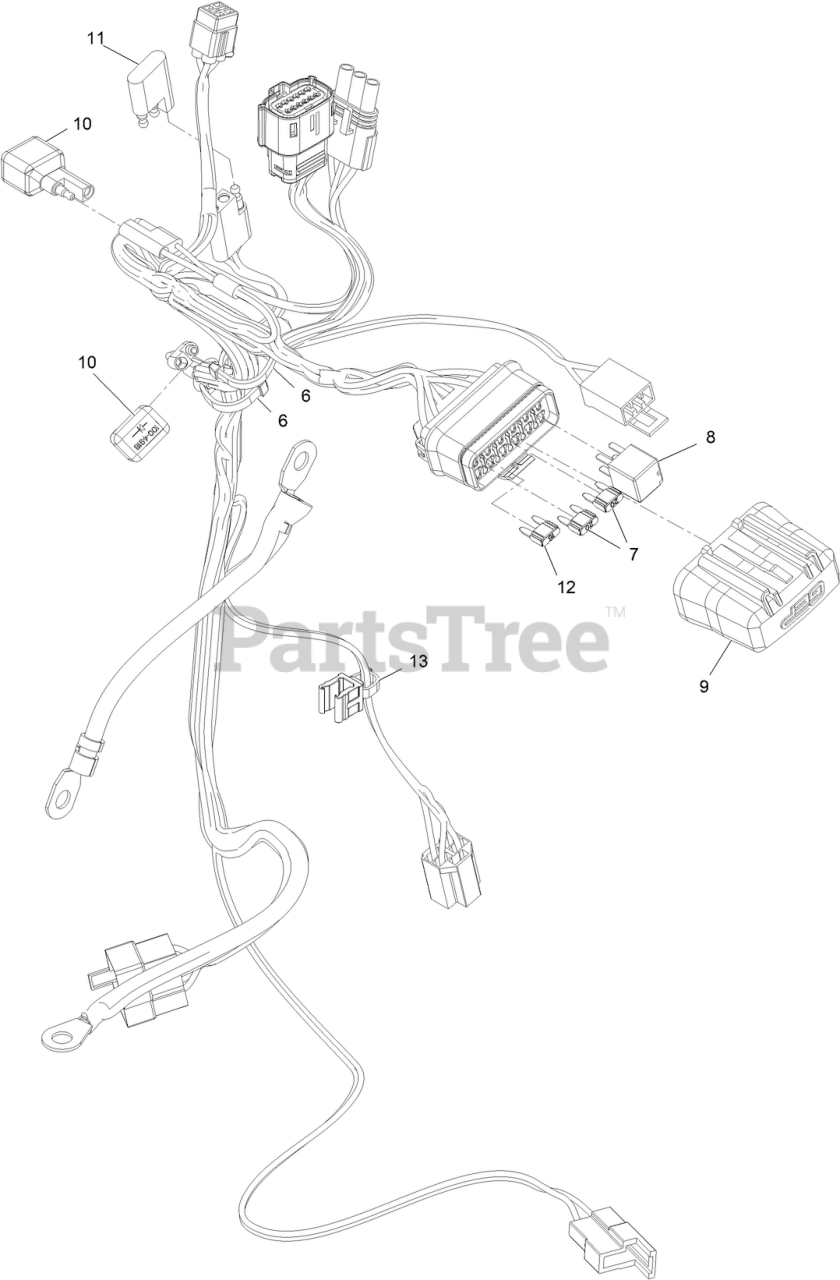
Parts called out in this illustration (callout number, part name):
6	CLIP-TIE
7	FUSE-MINI BLADE, 20 AMP
8	RELAY-MICRO
9	COVER-BLOCK, FUSE
11	Cap-Plug
12	FUSE-MINI BLADE, 15 AMP
13	Clip-Edge W/Tie, Perpendicular
